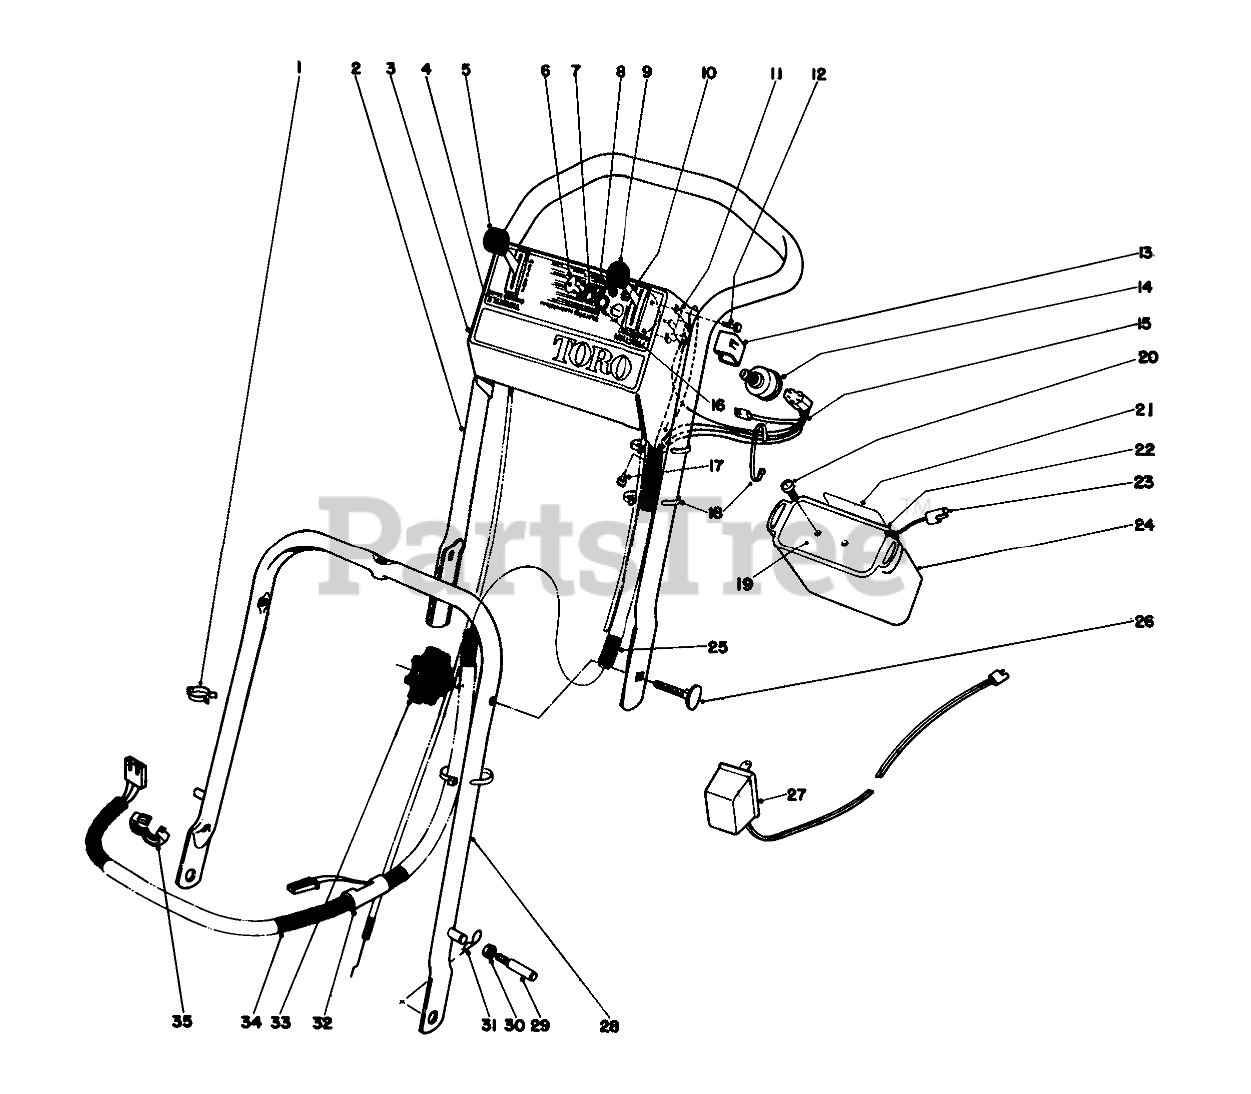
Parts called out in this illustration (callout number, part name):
2	UPPER HANDLE
3	Control Plate
4	Decal Control Plate
5	Control Throttle
6	Key
7	NUT-HH
8	NUT-HEX
9	Traction Control
10	WASHER-FLAT
11	CONTROL SWITCH
12	SCREW-HH
13	Cover Switch
14	SWITCH-STARTER
15	Wire Harness
16	WASHER-TOOTH, INTERNAL
17	SCREW-HWHTF
18	TIE-CABLE
19	BATTERY COVER
20	10-190X1/2 PAN HD SCR
21	Decal
22	Battery Assembly (Incl. Ref. #19-21 & 23-24)
23	Plug & Wire
24	Battery Case
25	Cover Wiring Harnes Upper
26	SCREW-HANDLE
27	Charger
28	LOWER HANDLE ASM
29	HANDLE PIN
30	Nut
31	PIN-COTTER, HAIR
32	Breakout Fitting
34	Cover Wiring Harness Lower
35	RING FITTING
